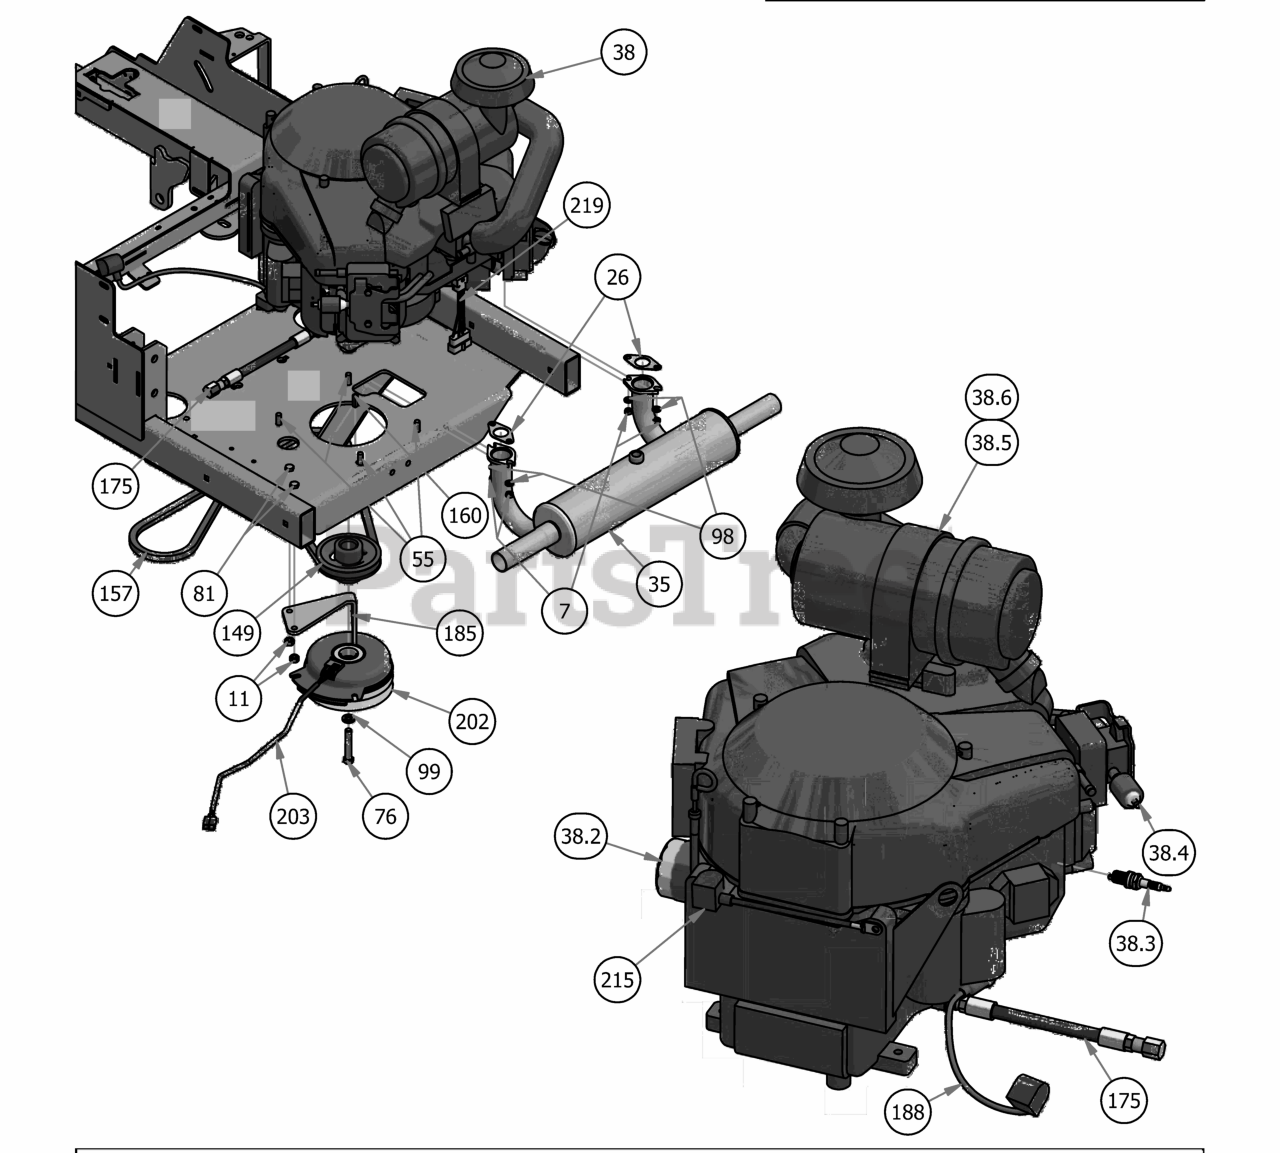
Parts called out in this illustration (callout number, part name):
7	M8-1.25 Zinc Nut
11	3/8" Hex Nut
26	Exhaust Gasket for 23 Vanguard
35	Muffler for 36Hp Vanguard
38	993cc Vanguard Engine
38.2	Oil Filter
38.3	Spark Plug
38.4	Universal Inline Fuel Filter
38.5	Canister Air Filter- Inner
38.6	Canister Air Filter- Outer
55	3/8 x 1 1/8 bolt
76	7/16" x 2 1/2" Hex Bolt
81	3/8" x 1" Hex Bolt
98	5/16" Lock Washer
99	7/16" Lock Washer
149	4 3/4 Motor Pulley
157	2019 Rogue Pump Belt 68"
160	1/4" x 1" Key
175	14 mm Oil drain Hose 993cc Vanguard
185	PTO Engager Holder
188	24" Red Battery Cable
202	Clutch Assembly
203	Clutch Pigtail
204	2019 Veritical Suspension Frame
215	Starter Cable
219	2019 Harness Adaptor - Vanguard 37 EFI Vert/Horiz
